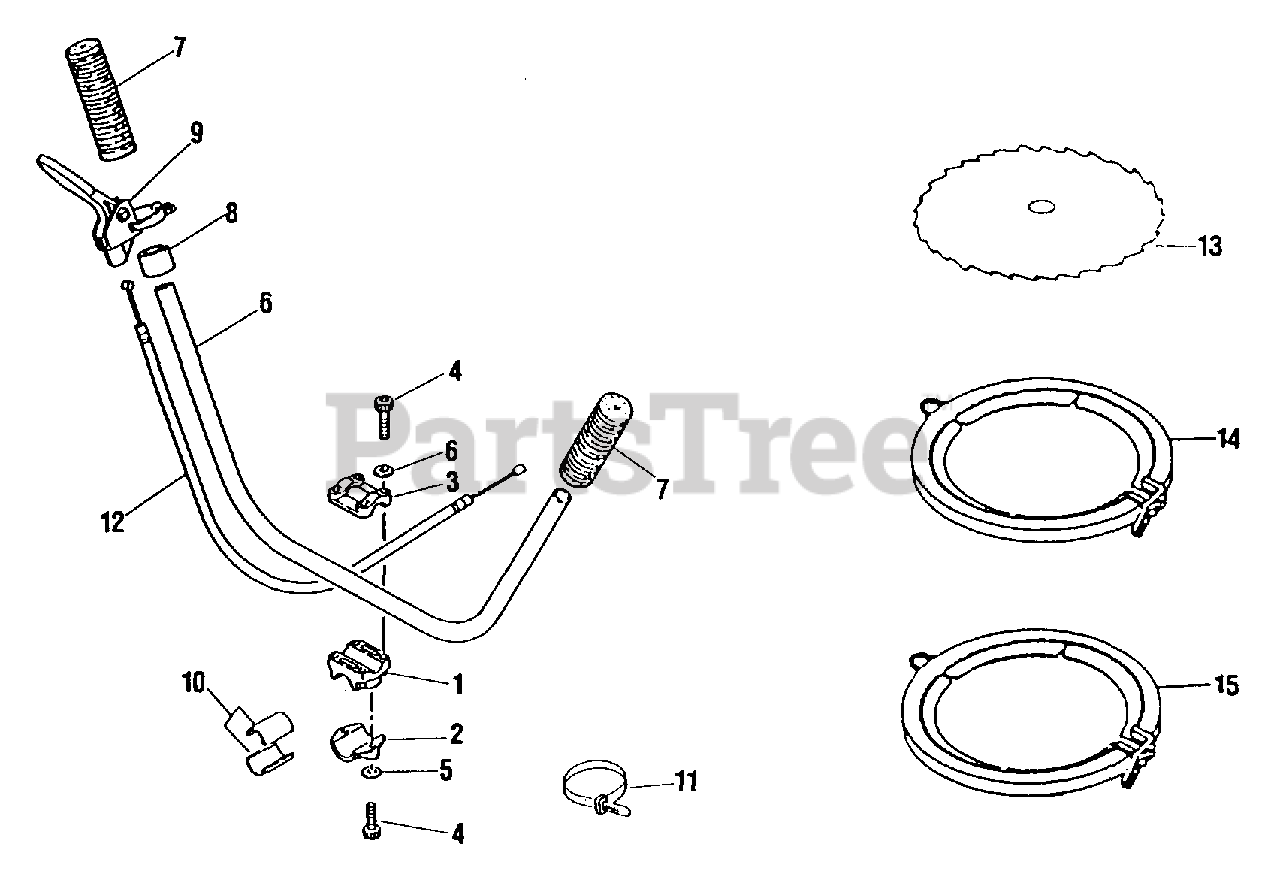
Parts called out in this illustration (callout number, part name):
1	BRACKET, HANDLE
2	CLAMP, LOWER
3	BRACKET, UPPER
4	BOLT M5×25
5	WASHER, FLAT 5.5×10×0.8
6	HANDLE
7	GRIP, HANDLE
8	COLLAR
9	THROTTLE LEVER ASSY
11	CLAMP
12	CABLE, THROTTLE
13	BLADE - 30 TOOTH -- 8"
14	COVER - 8"
15	COVER- 9"
